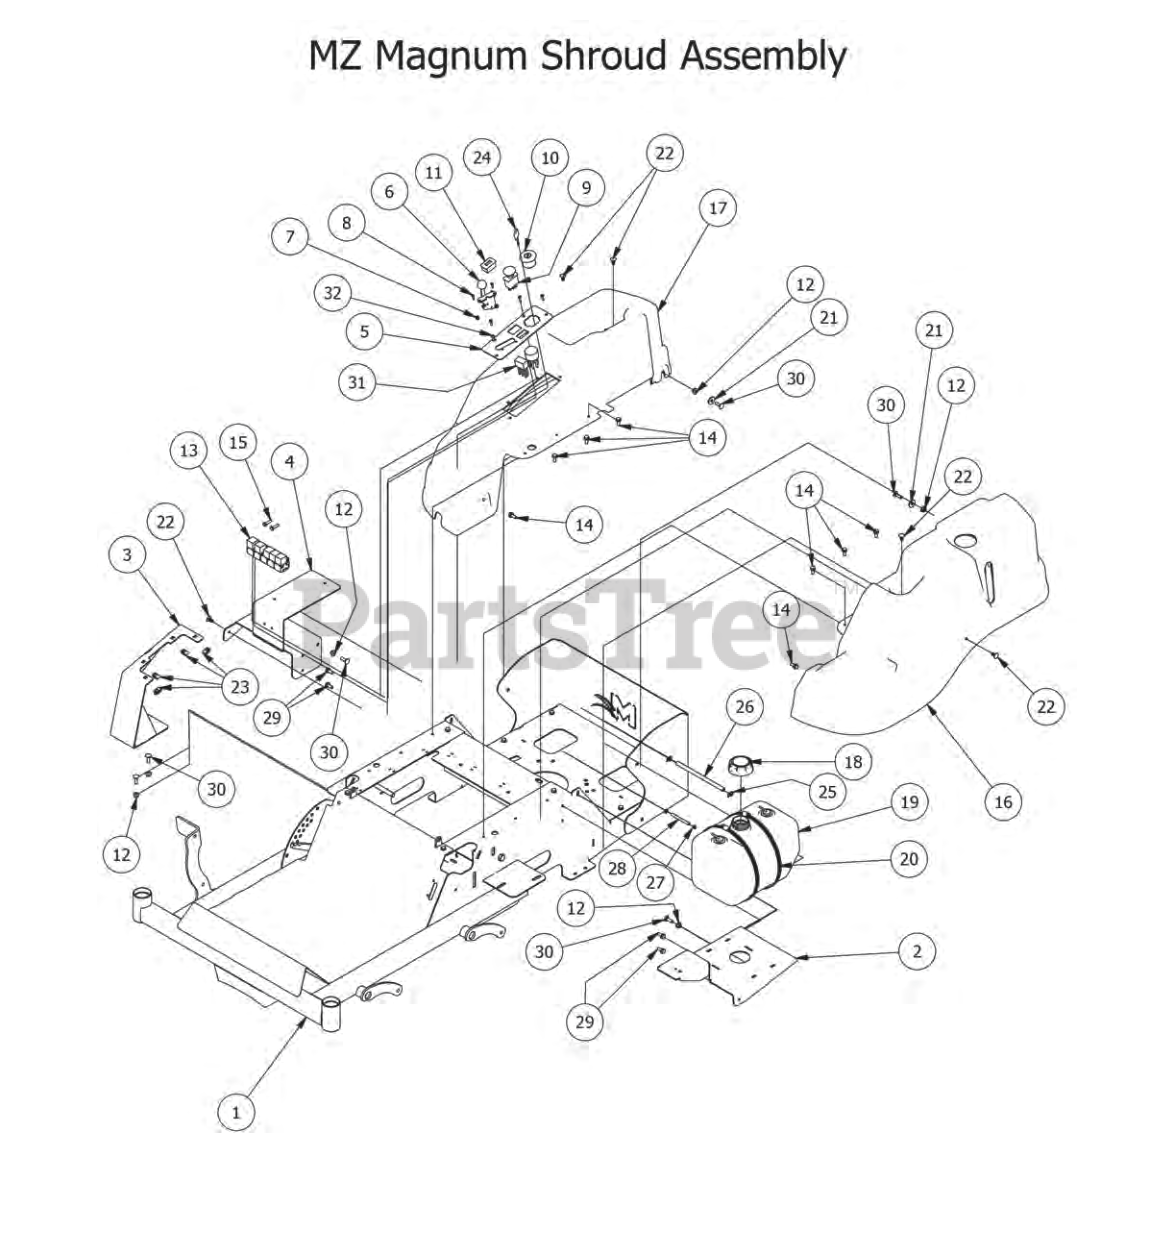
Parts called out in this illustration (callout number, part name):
1	2014 54" MZ Magnum Frame
2	MZ Magnum Gas Tank Bracket Assy
3	MZ Magnum Shroud Control Support Assy
4	MZ Magnum Shroud Storage Support Assy
5	Control Panel New MZ
6	Throttle Lever W/Choke
7	10-24 Nylon Insert Locknut
8	10-24 X 5/8 BS C/S 18-8 SS
9	PTO Engager
10	Ignition Switch
11	Tachometer
12	5/16" Nylon Flange Nut
13	Relay Terminal
14	5/16 x 3/4 washer head type F screw
15	1/4 x 1 Hex Head tek screw
16	2013 Magnum Left Fender Shroud
17	2013 Magnum Right Fender Shroud
18	Fuel Cap 2013 Magnum-080165AE
19	2.5 Gal EPA Tank Assy-071145AE
20	MZ Magnum Tank Clamp-63164
21	.360 ID Plastic Washer
22	Ratchet Fastener
23	10-24 "U" Nut
24	Ignition Key
25	1/4 fuel clamp
26	1/4" fuel line hose
27	1/4" vinyl clamp
28	1/4" vinyl tubing
29	5/16 x 3/4 washer head type F screw
30	5/16" x 1" Carriage Bolt
31	wiring harness
32	10-24 x 1 BS C/S 18-8 SS
